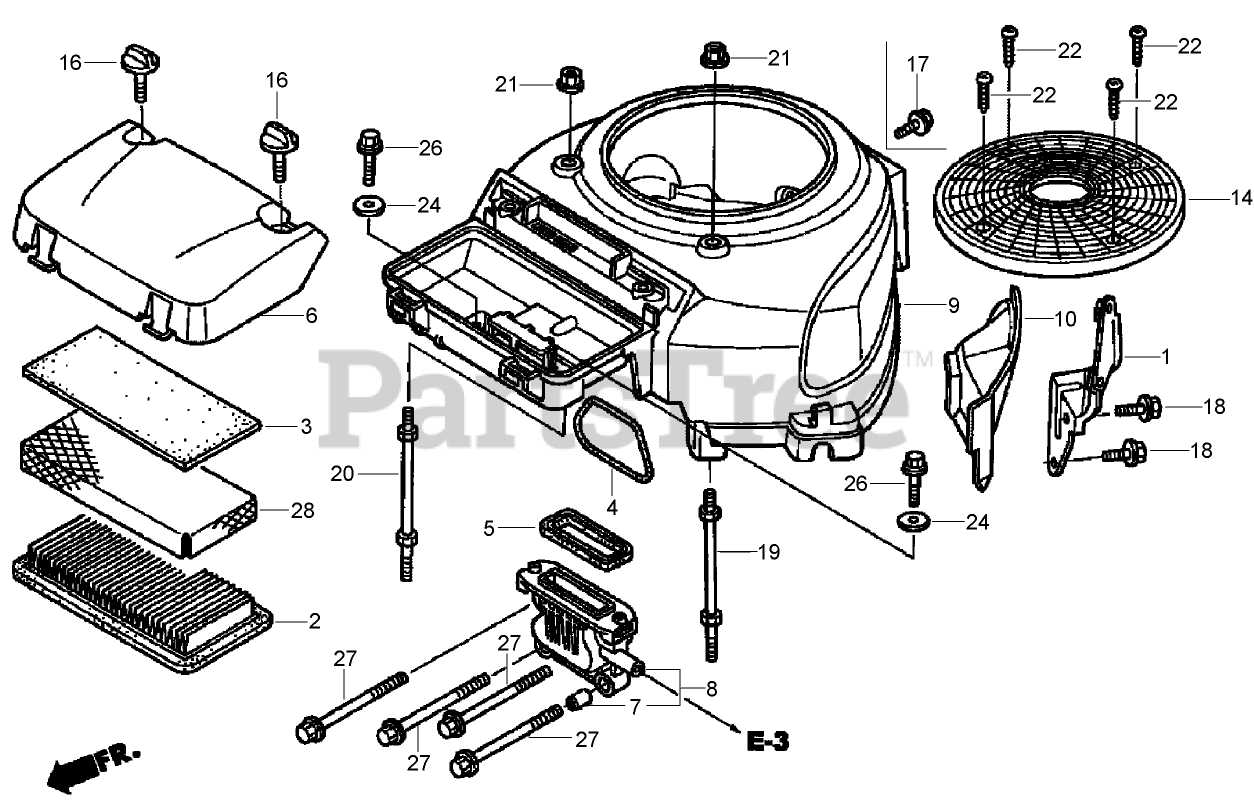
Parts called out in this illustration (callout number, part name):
1	STAY-PUMP, FUEL
2	ELEMENT-CLEANER, AIR
3	FILTER (OUTER)
4	GASKET-CLEANER, AIR
5	SEAL-HOUSING, AIR CLEANER
6	COVER-CLEANER, AIR
7	COLLAR A-CLEANER, AIR
8	ELBOW-CLEANER, AIR
9	COVER-FAN (NH1) (BLACK)
10	PLATE-SIDE
14	GRID-SCREEN NH105 (MATTE BLACK)
16	BOLT (6MM)
17	BOLT-FLANGE (6X14) (CT200)
18	BOLT-FLANGE (6X14) (C T200)
19	BOLT-STUD, LEFT (IGNITION COIL)
20	BOLT-STUD, RIGHT (IGNITION COIL)
21	NUT-FLANGE (6MM)
22	SCREW-TAPPING (4X16)
22	SCREW-TAPPING (4X30) (P0)
24	WASHER-PLAIN (6MM)
26	BOLT-FLANGE (6X12)
27	BOLT-FLANGE (6X100)
28	GRID-CLEANER, AIR
